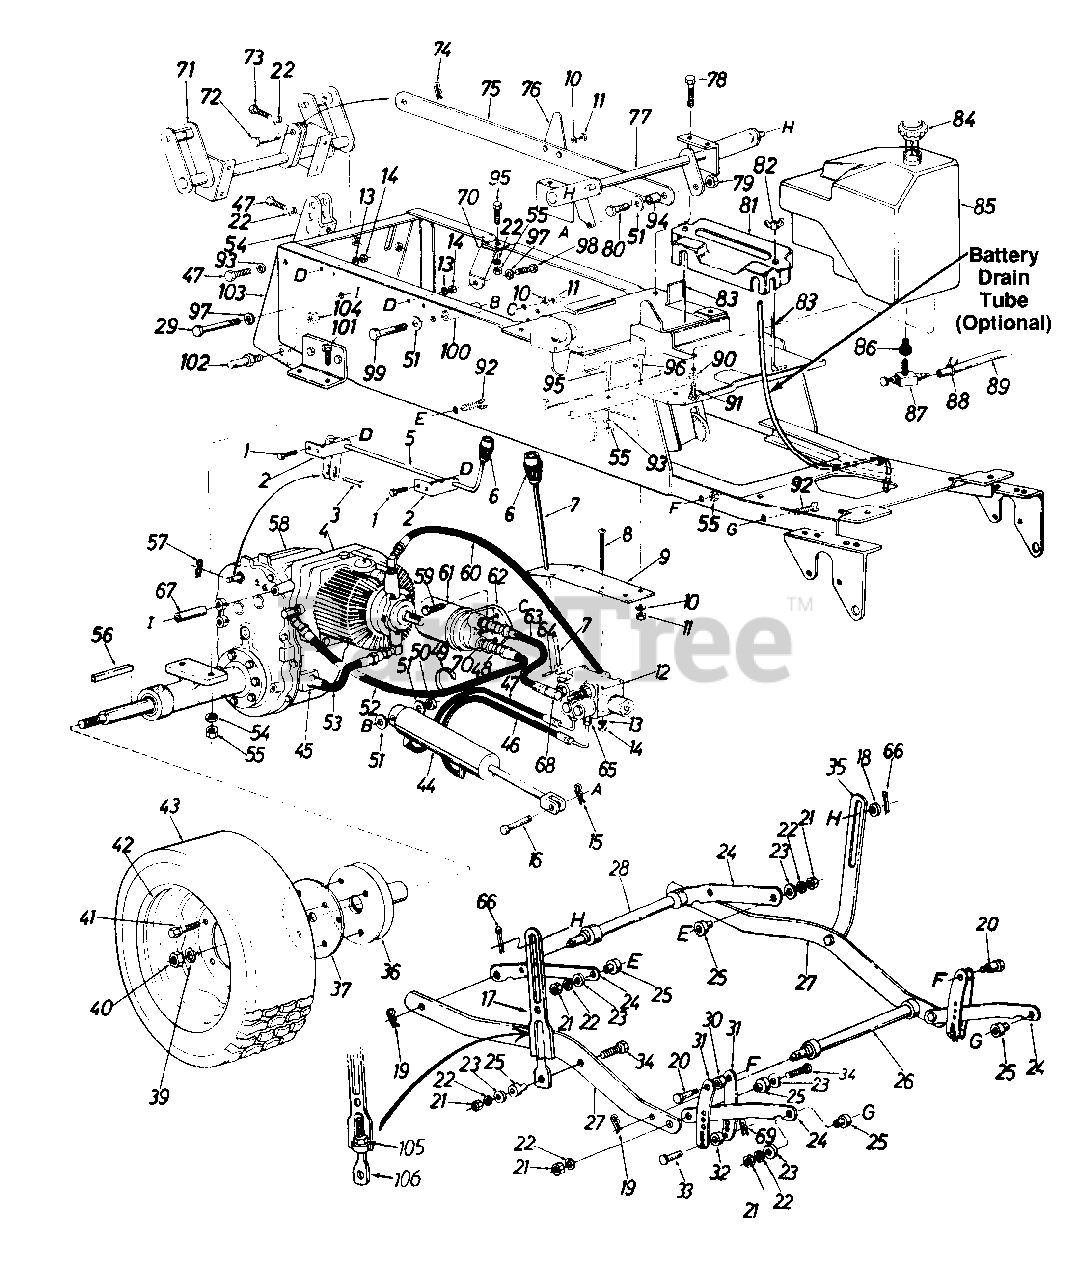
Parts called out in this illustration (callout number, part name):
1	Hex Bolt 1/4-20 x .75" Lg.
4	Hydrostatic Pump Comp.
5	Hi-Lo Control Handle Ass'y.
6	Shift Knob
7	Cylinder Control Handle Ass'y.
8	Truss Mach. Scr. 1/4-20 x 3.00" Lg.
11	Hex Nut 5/16-18 Thd.
12	Valve Ass'y. Comp.
13	L-Wash. 1/4" I.D.
14	Hex Nut 1/4-20 Thd.
15	Hairpin Cotter 1/2" Dia.
16	Clevis Pin 1/2" Dia.
17	Adj. Deck Link
18	Fl-Wash. .62" I.D. x 1.12"
19	Hairpin Cotter
20	Shld. Bolt .498" Dia. x .66"
21	Hex Nut 3/8-24 Thd.
22	L-Wash. 3/8" I.D. - H.D.
23	Fl-Wash. .38" I.D. x 1.00"
26	Cross Shaft Ass'y. - Front
29	Hex Bolt 1/2-13 x 2.75"
30	Collar .50" I.D. x 1.0"
33	Clevis Pin 3/8" Dia.
34	Hex Bolt 3/8-24 x 1.50" Lg. - Grade 5
39	L-Wash. 3/4" I.D.
40	Hex Ins. L-Nut 3/4-16 Thd.
41	Wheel Lug Bolt
44	Hydraulic Cylinder
45	7/8-14 UNF-2A Thd. 5/8 Tube Fitting
46	Valve to Cylinder Hose - 20"
47	Hex Bolt 3/8-16 x .75" Lg. - Grade 5
48	Bushing Reducer 1/2-14 NPTF to 3/8-18 NPTF
49	Cable Tie
50	Hex Jam Nut 1/2-20 Thd.
51	Fl-Wash. .50" I.D. x 1.25
52	Filter Return Hose 24" Lg.
53	Pump Tube Ass'y.
55	Hex Nut 3/8-16 Thd.
56	Sq. Key 1/4" x 1/4" x 2"
57	Hairpin Cotter 1/4" Dia.
58	Peerless Transaxle
59	Hex Bolt 5/16-18 x 1.25"
60	Pump to Valve Hose
61	Fram Filter Ass'y. PH-16
63	Valve to Filter Hose - 8.38"
64	Spring Pin Spiral 1/8" Dia.
65	Flare Adapter
66	Cotter Pin 1/8" Dia. x 1.0"
68	Adapter 9/16-18 to 9/16-18
69	Hairpin Cotter
70	Transmission Brace
73	Hex Scr. 3/8-16 x 1.00" Lg. Grade 5
74	Cotter Pin 1/8" Dia. x 1.25"
79	Hex Cent. L-Nut 1/2-20 Thd.
80	Hex Scr. 1/2-20 x 1.25" Lg.
81	Battery Cover
82	Wing Nut 1/4-20 Thd.
83	Battery Hold Down Rods
84	Gas Tank Cap
85	Gas Tank Ass'y.
86	Bushing
87	Fuel Shut-Off Valve with Screen
88	Gas Line Clamp 1/2"
89	Gas Line 26" Lg.
91	Hex Scr. 1/4-20 x .38" Lg.
92	Hex Scr. 3/8-24 x 1.50" Lg."
93	L-Wash. 3/8" Scr.
94	Push Bar Sleeve
95	Hex Scr. 3/8-16 x 1.00" Lg. - Grade 5
96	Hex Scr. 5/16-18 x .75" Lg.
97	L-Wash. 1/2" Scr.
98	Hex Scr. 1/2-13 x 1.25" Lg.
99	Hex Scr. 1/2-20 x 3 1/2" Lg. - Grade 5
100	Spacer for Cylinder
101	Hex Scr. 3/8-16 x 1.75" Lg.
102	Link Clevis Pin
105	Hex Nut 1/2-13 Thd.
106	Eye Bolt
